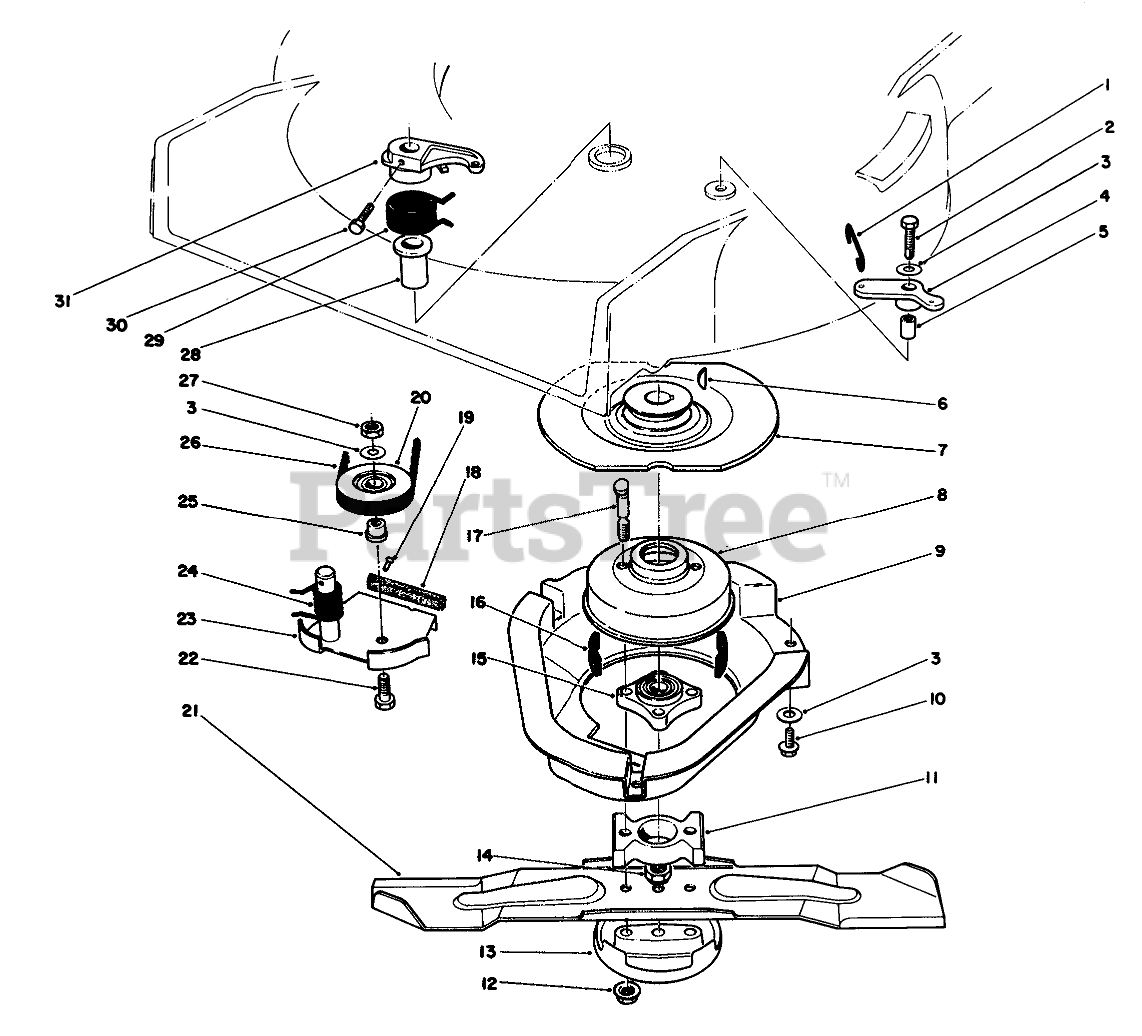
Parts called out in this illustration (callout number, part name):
1	LINK-CONTROL
2	SCREW-HH
3	WASHER-PLAIN
4	BELLCRANK
5	SLEEVE-BELLCRANK
6	KEY-WOODRUFF
7	Flywheel
8	Brake Drum
9	SHIELD BBC
10	SCREW-HWHTF
11	Spacer Blade
12	NUT-LOCK
13	Anti Scalp Cup
14	NUT-LOCK, NI
15	HUB ASM
16	DAMPENER-VIBRATION
17	BOLT-BLADE
18	Paid
19	.185 DIA X .375 RT +
20	PULLEY-IDLER
21	BLADE-21in
22	SCREW-HH
23	Brake Plate (Incl. Ref. #20 & 21)
24	SPRING-TORSION
25	HUB-PULLEY, IDLER
26	V-BELT
27	NUT-LOCK, NI
28	BUSHING PM
29	SPRING-TORSION
30	SCREW-HH
31	LEVER
